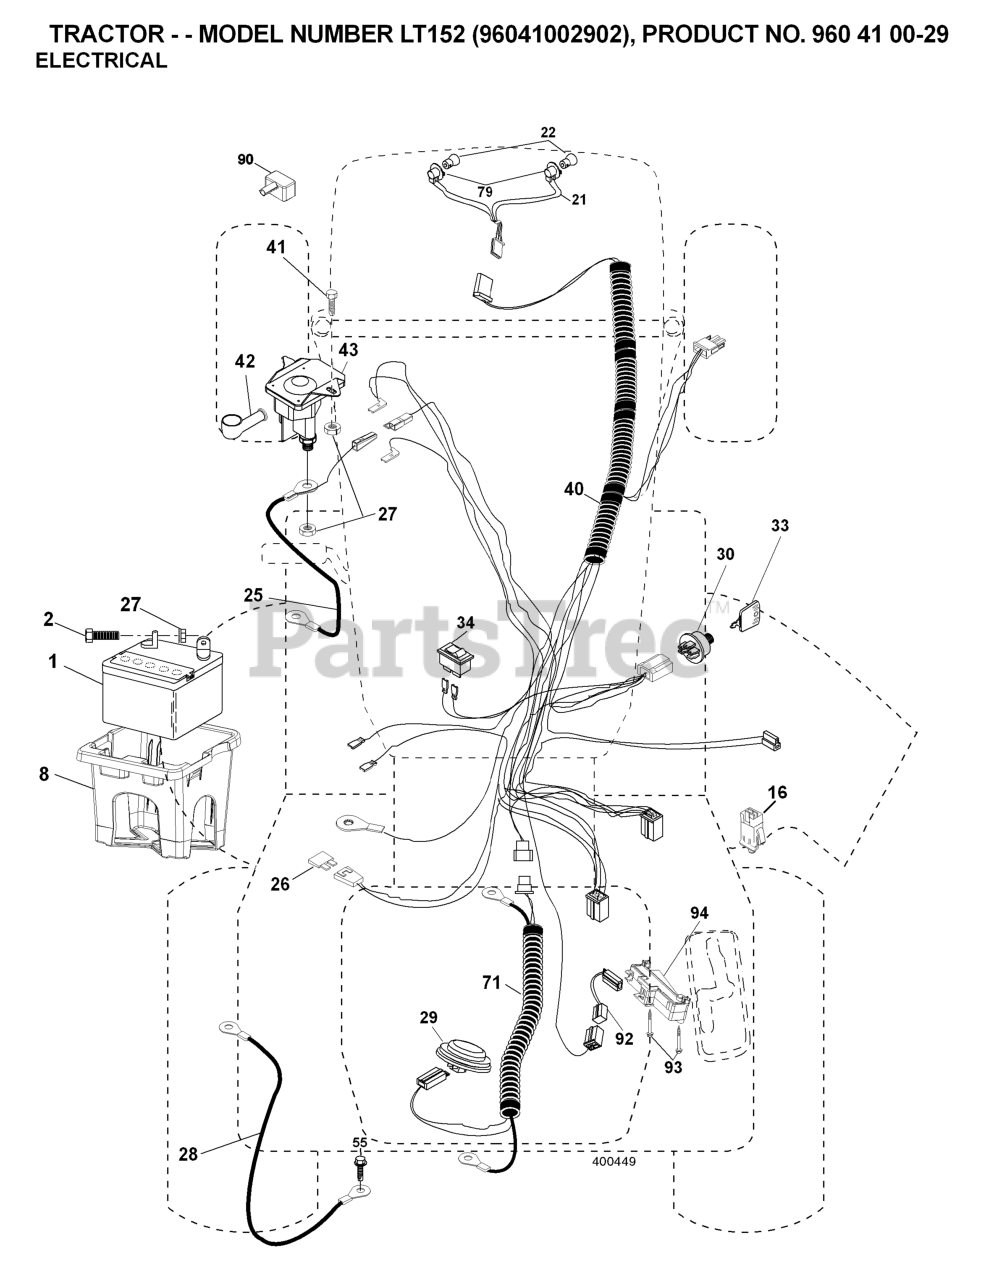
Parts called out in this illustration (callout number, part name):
1	BATTERY 12V .35 AMP
2	BOLT.HEX.1/4.X.3/4.DICHROMATE
8	BOX.BATTERY.MNT.REAR.L
16	SWITCH INTERLOOK PUSH-IN
21	HARNESS.LIGHT W/4152J BULBS
25	CABLE.STARTER.6GA.RED.
26	FUSE 20AMP
27	NUT
28	CABLE.BLACK.18"REAR.BA
29	SWITCH.SEAT.DELTA.OPC.
30	SWITCH.IGN.DELTA.W.LGH.ROS
33	KEY MLD GEN DELTA
40	HARNESS IGN. DASH
41	SCREW
42	TERMINAL COVER
43	SOLENOID.W/BRASS.PLUNGER
55	SCREW 5/16"
71	HARNESS.IGN.CHASS.TEX.REAR.BAT
79	BULB HOLDER ASM.
90	COVER, TERMINAL BATTERY
92	HARNESS.PIGTAIL.CONSLE
93	SCREW.PLASTITE
94	MODULE.REVERSE.ROS
